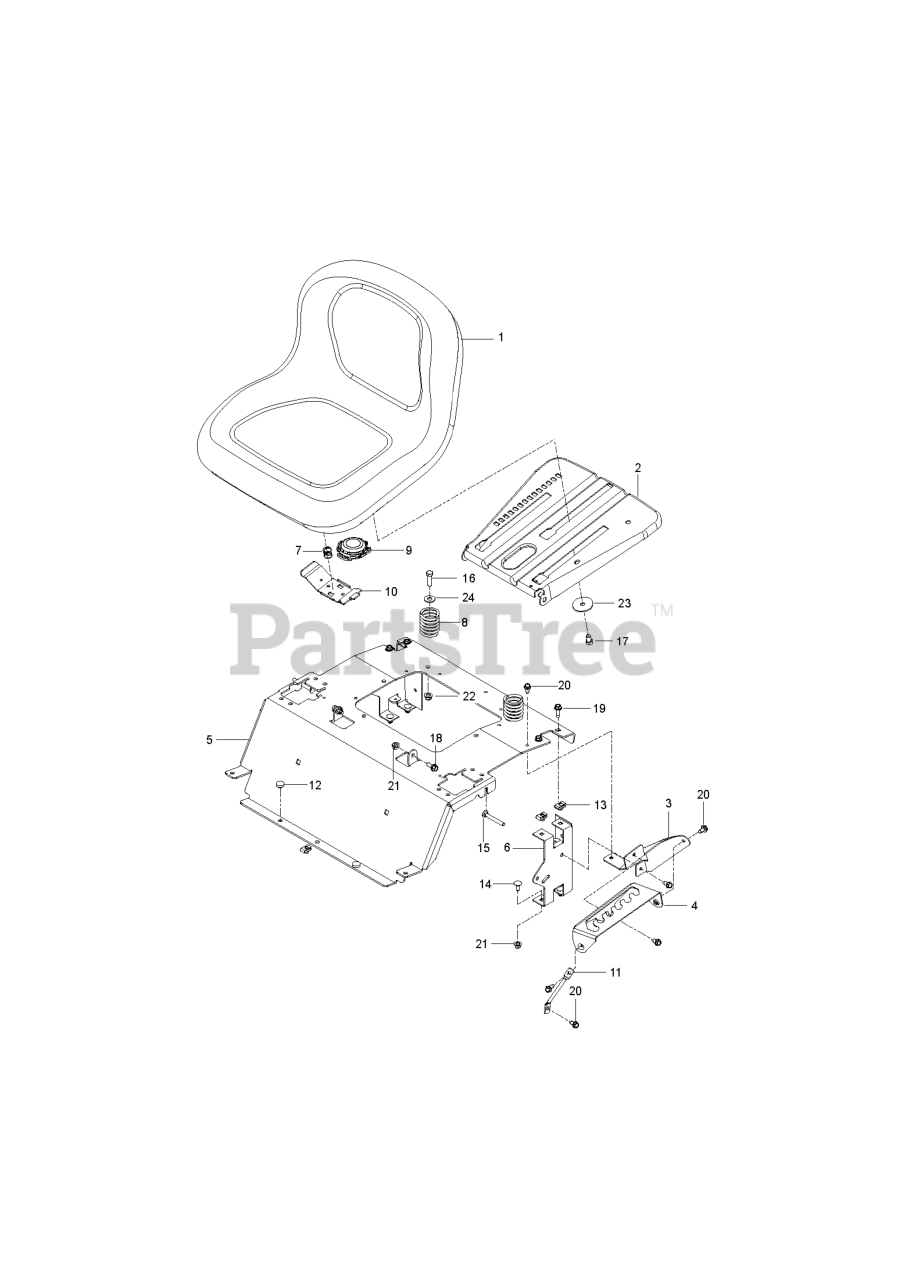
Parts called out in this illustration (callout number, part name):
1	SEAT.TH150.MS498.GRY.HUSQ.TEX
2	PLATE.PNT.SEAT.SLIDE.3PT.EDIP
3	PLATE.SUPPORT.DECK.LIFT.X431
4	PLATE.DECK.LIFT.X431
5	SUPPORT SEAT ORANGE
5	SUPPORT.SEAT.RZ.HUSQ.ORANGE
6	SUPPORT REAR SEAT BLACK
7	SPRING.LATCH.SEAT.TEX
8	SPRING.COMPRESSION.SEAT.BLACK
8	SPRING.COMPRESS.SEAT.TAPERED
9	SWITCH.SEAT.DELTA.OPC.
9	SWITCH.SEAT.OPC.GRY.BUTTON/CAP
10	HANDLE.SLIDE.SEAT.TEX.BLACK
11	SUPPORT.LEG.DECK.LIFT
12	GROMMET.BUMPER
13	U-CLIP 5/16-18 NUT RETAINER
14	RP BOLT 5/16-18 X3/4 ZN/YEL GR
15	RHSNB 5/16-18 X 2-1/2 GR5 ZD
16	BOLT
17	HCS 3/8-16 X 5/8 GR 5 ZD
17	BOLT
18	BOLT, SHOULDER
19	SCREW.THDROL.5/16-18X3/4.TTY
20	BOLT.5/16HEX.WHS.HD
21	5/16-18 NYLOC FLANGE NUT
22	NUT 3/8-16 HEX FLG NYLOC ZD
23	RP WASHER 3/8 FLAT
23	WASHER, 3/8 SPEC
24	WASHER.WINGED.3/8ID.1.5OD
